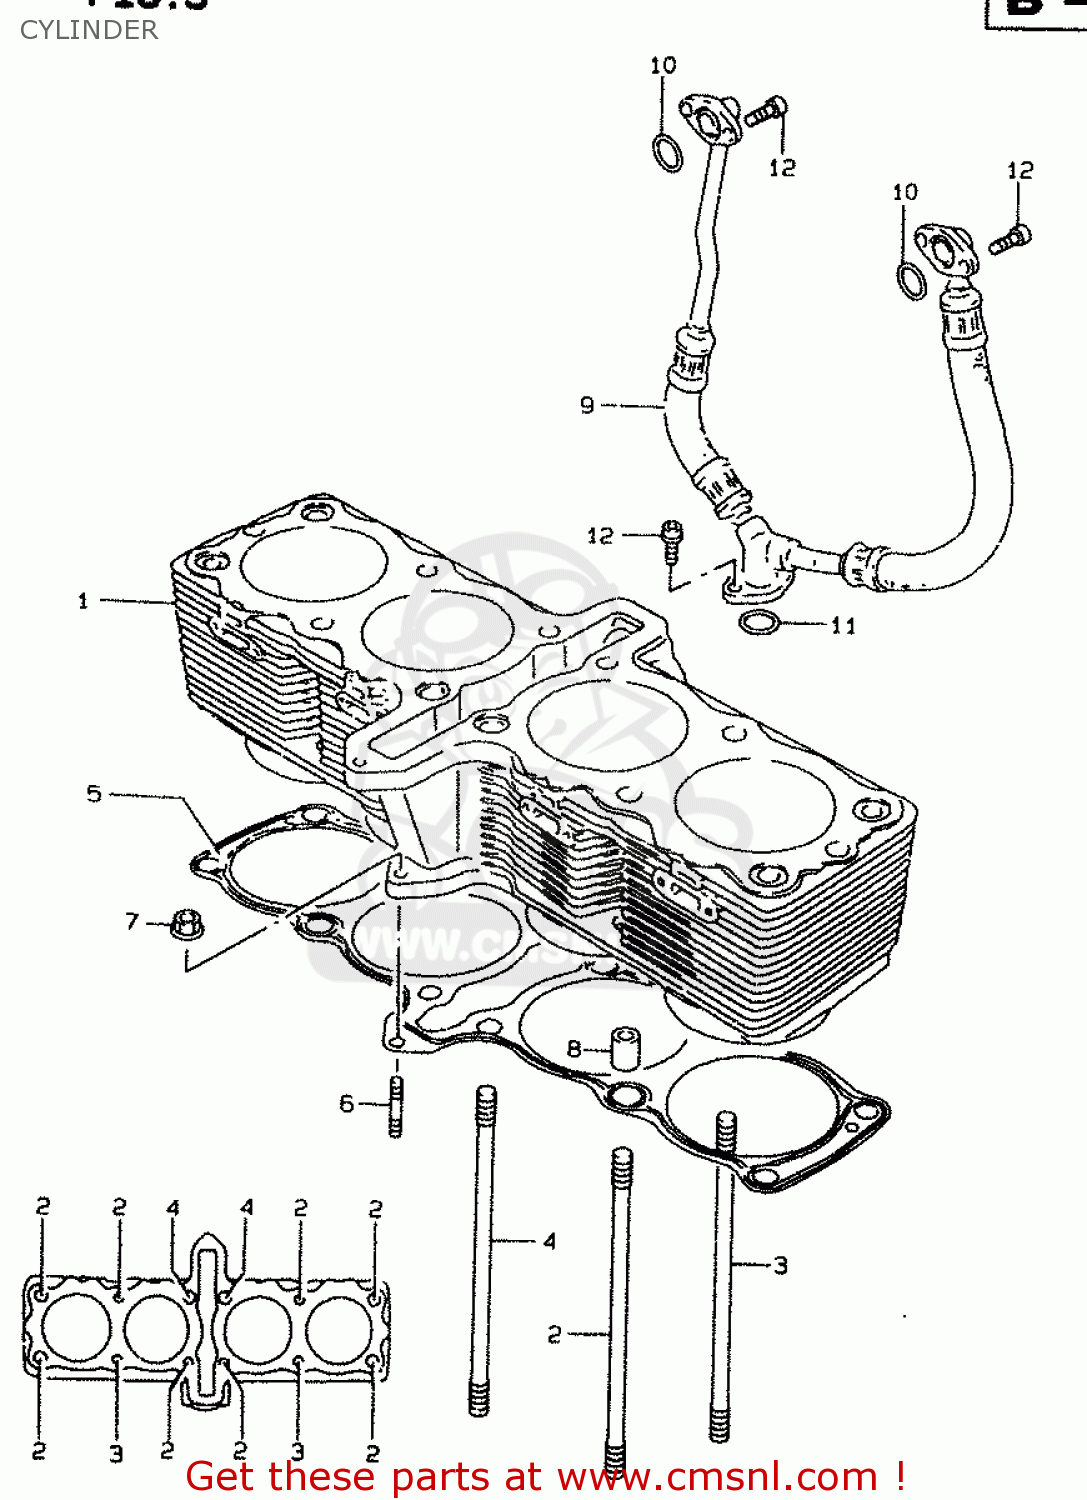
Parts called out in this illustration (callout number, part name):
1	CYLINDER
2	BOLT,STUD
3	BOLT,STUD
4	BOLT,STUD
5	GASKET,CYLINDER (NAS)
6	STUD,M6X1X32
7	NUT
8	PIN(13X10.4X20)
9	HOSE,OIL HEAD COOLER
10	O RING(D:2.5,ID:13.8)
11	O RING(D:2.4,ID:15.8)
12	BOLT,OIL FILLE
